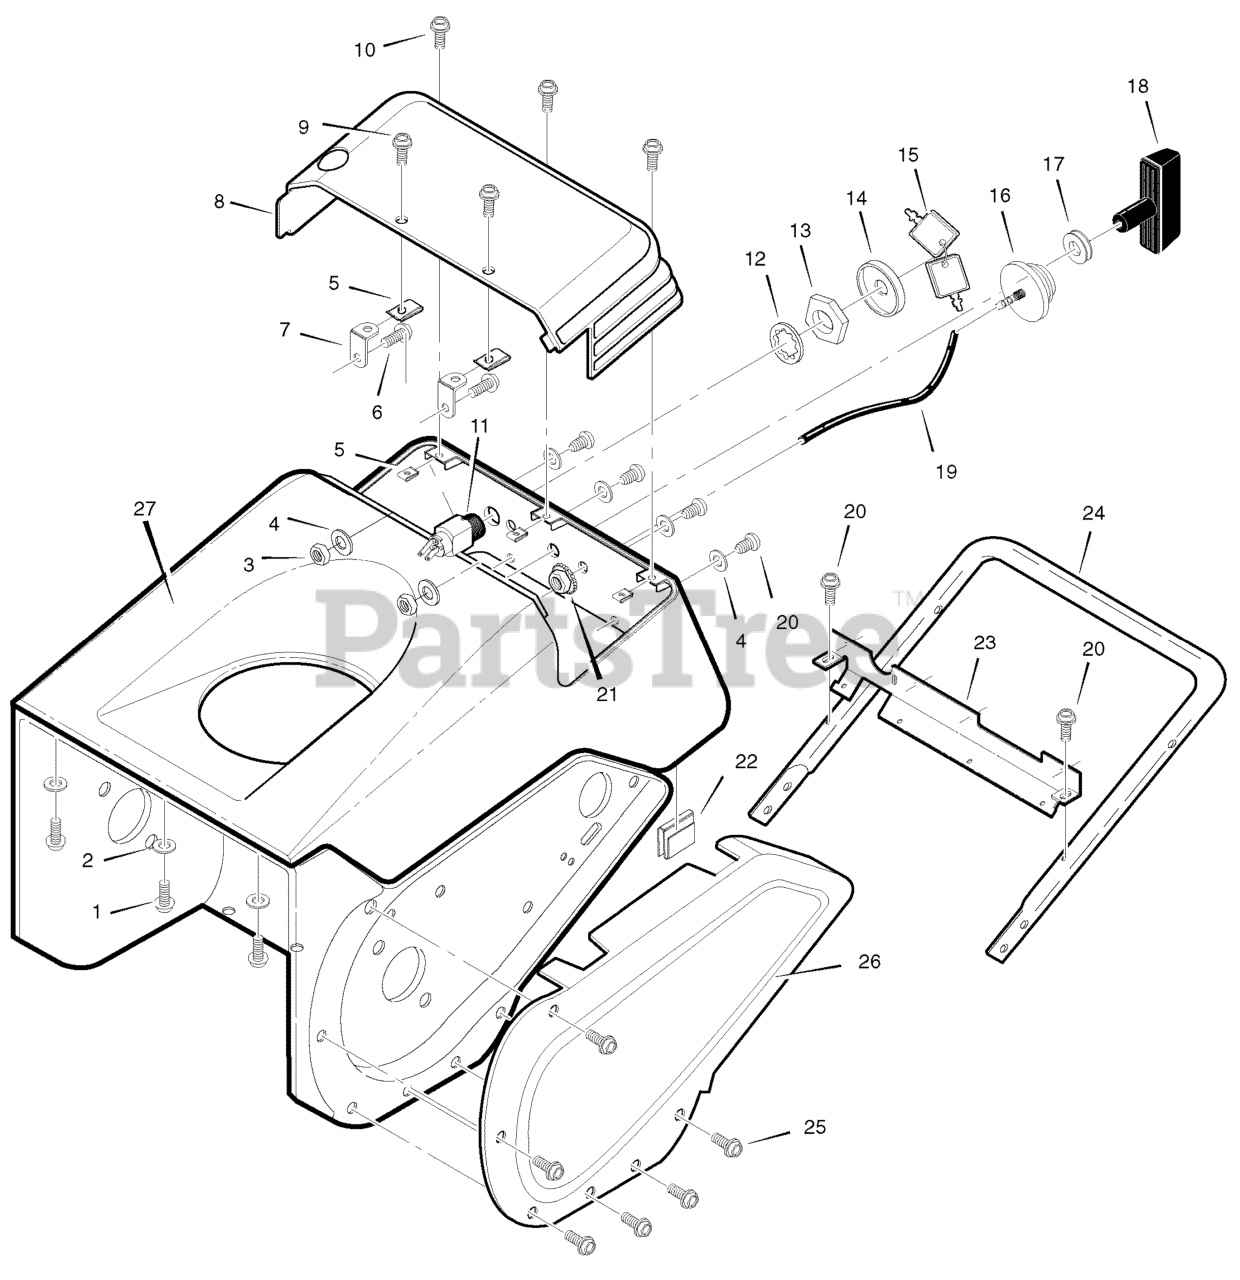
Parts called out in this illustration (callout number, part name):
1	SCREW 10-14x.63
2	WASHER, FLAT
3	NUT, LOCK 10-24
4	WASHER, FLAT
5	NUT, U TYPE
6	SCREW 10-24x.50
7	BRACKET, ACCESS COVER
8	COVER, ENGINE ACCESS
9	SCREW 10-16x.62
10	SCREW 10-16x.75
11	INGNITION SWITCH
12	WASHER, INTERNAL LOCK
13	NUT, .62-32 PLASTIC
14	BOOT, SWITCH
15	KEYS & RING
16	PRIMER BULB
17	GROMMET & WASHER
18	KNOB, STANDARD T
19	HOSE, PRIMER
20	SCREW 10-24x.63
21	NUT .25-20 KEPS
23	BRACKET, SHROUD MTG
24	LOWER HANDLE
25	SCREW 10-24x.38
26	COVER, BELT
27	COVER, TOP
